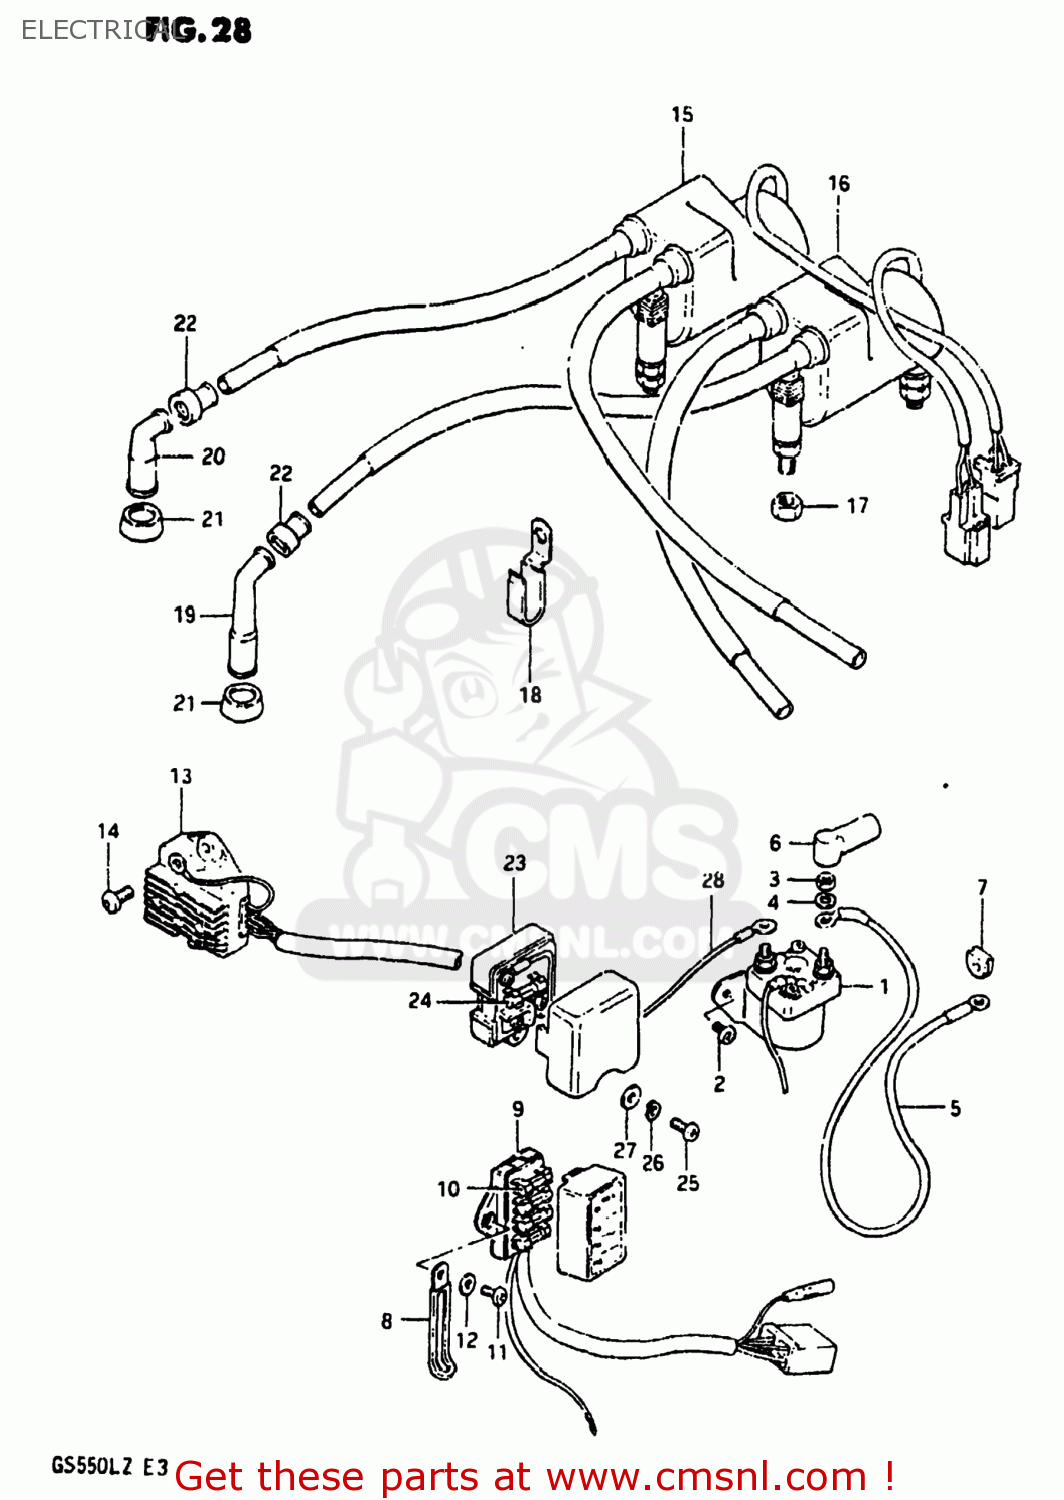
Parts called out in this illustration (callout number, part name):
1	RELAY ASSY,STARTING MOTOR
2	SCREW
3	NUT 6MM
4	LOCK WASHER
5	WIRE,STARTER MOTOR LEAD
6	CAP,STARTER RELAY
7	GROMMET,STARTER CABLE
8	CLAMP
9	BOX ASSEMBLY,FUSE
10	FUSE(15A)
11	SCREW 6X12
12	WASHER
13	RECTIFIER ASSEMBLY
14	SCREW
15	COIL ASSEMBLY,IGNITION
16	COIL ASSEMBLY,IGNITION
17	NUT
18	CLAMP
19	CAP,SPARK PLUG
20	CAP,SPARK PLUG
21	SEAL,SPARK PLUG
22	SEAL,SPARK PLU
23	TERMINAL ASSEMBLY,POWER SO
24	FUSE(10A)
25	SCREW
26	LOCK WASHER
27	WASHER
28	WIRE,POWER SOURCE LEAD
